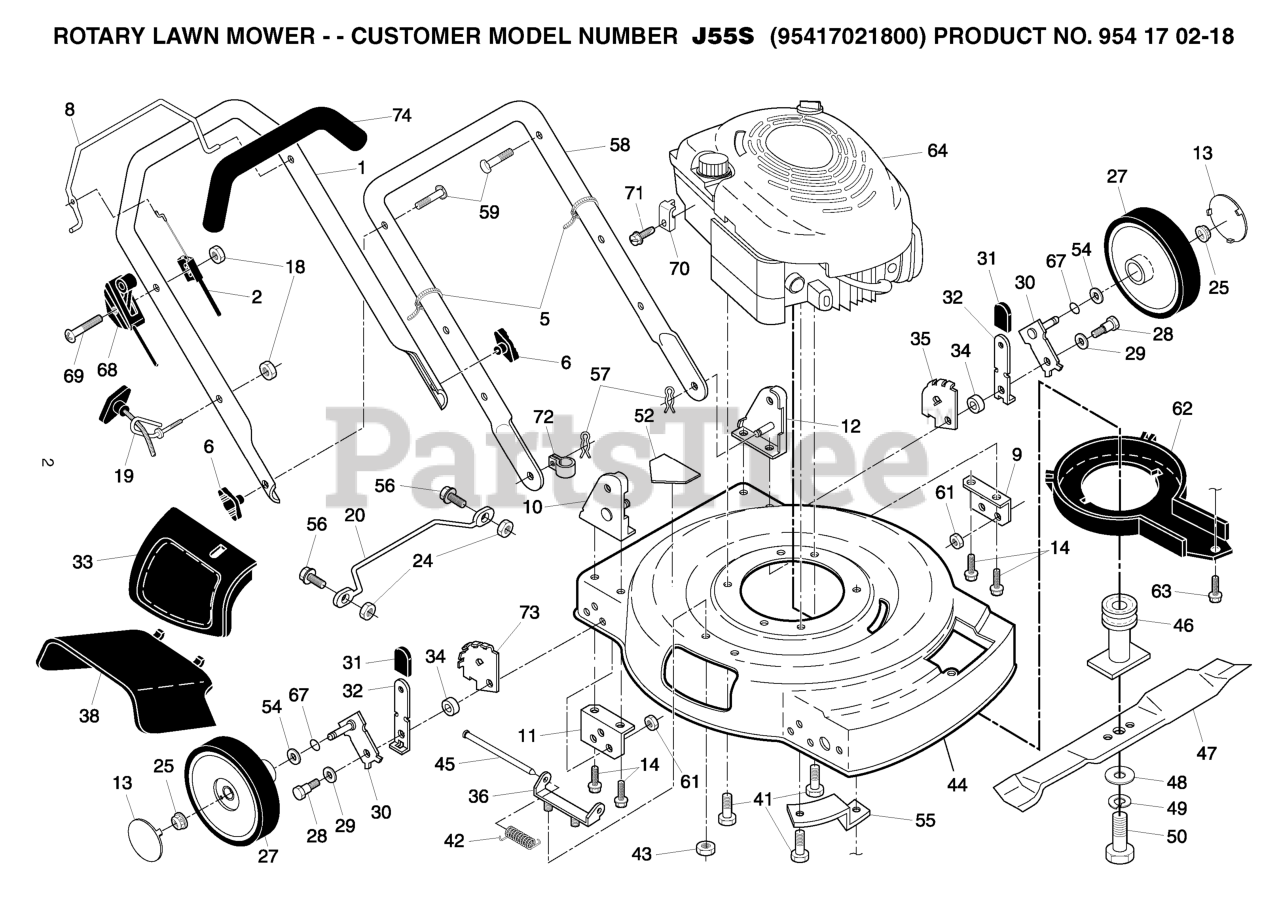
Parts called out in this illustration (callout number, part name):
1	HANDLE.UP.DLX.COMF.W/GRIP.GREY
2	ENGINE ZONE CONTROL CABLE
5	TIE GUIDE
6	KNOB, DEFLECTOR
8	BAIL.COMF.FWGD.668.ORANGE.WALK
9	GUARD.SLKSCR.BELT.
10	HANDLE BRACKET ASM. RH
11	Support Bracket, Handle, RH
12	HANDLE BRACKET ASM. LH
13	HUBCAP.8".GREY
14	SCREW.5/16-18X3/4
18	NUT
19	ROPE, GUIDE
25	HEX FLANGE LOCKNT
27	WHEEL.8X2.PR.LP.RAD.GREY
28	BOLT
29	WASHER.BELLEVILLE (3 2 LB)
30	AXLE ARM
31	SELECTOR KNOB
33	DOOR.MULCH.22.EZ.MULCH.GREY
34	RP SPACER HT ADJ
35	BRACKET WHL ADJ
36	BRACKET.ASM.HOUSING.EZ.MUL
38	DEFLECTOR.GUARD.22..EZ.MULCH
41	BOLT 3/8-16X1-1/8
42	TORSION SPRING
43	LOCKNUT.NYLOC.1/4-20
45	ROD.HINGE.COMBI-C
46	BLADE ADAPTOR / PULLEY
47	BLADE.22.MULCH.SD/EZ
48	WASHER,HARDEN
49	LOCKWASHER
50	SCREW, HEX HD 3/8-24 X 1-3/8
52	DECAL.INTERNATIONL.CUTFINGER
54	WASHER.FLAT.1/2
55	BRACKET
56	REPL BY 817 02 10-08
57	HAIRPIN COTTER
58	HANDLE
59	BOLT, HANDLE 5/16-18X1.75
61	LOCKNUT PM
62	DEBRIS.SHIELD.21:.FGD
63	SCREW.HEX.WSH
67	O-RING
68	THROTTLE CONTROL
70	CABLE CLAMP(ENGINE)
71	SCREW.HEX.HEAD.WASHER.10-16
72	CLIP.CABLE.BLK
73	BRACKET WHL ADJ. NLA
74	GRIP.HANDLE.FOAM
